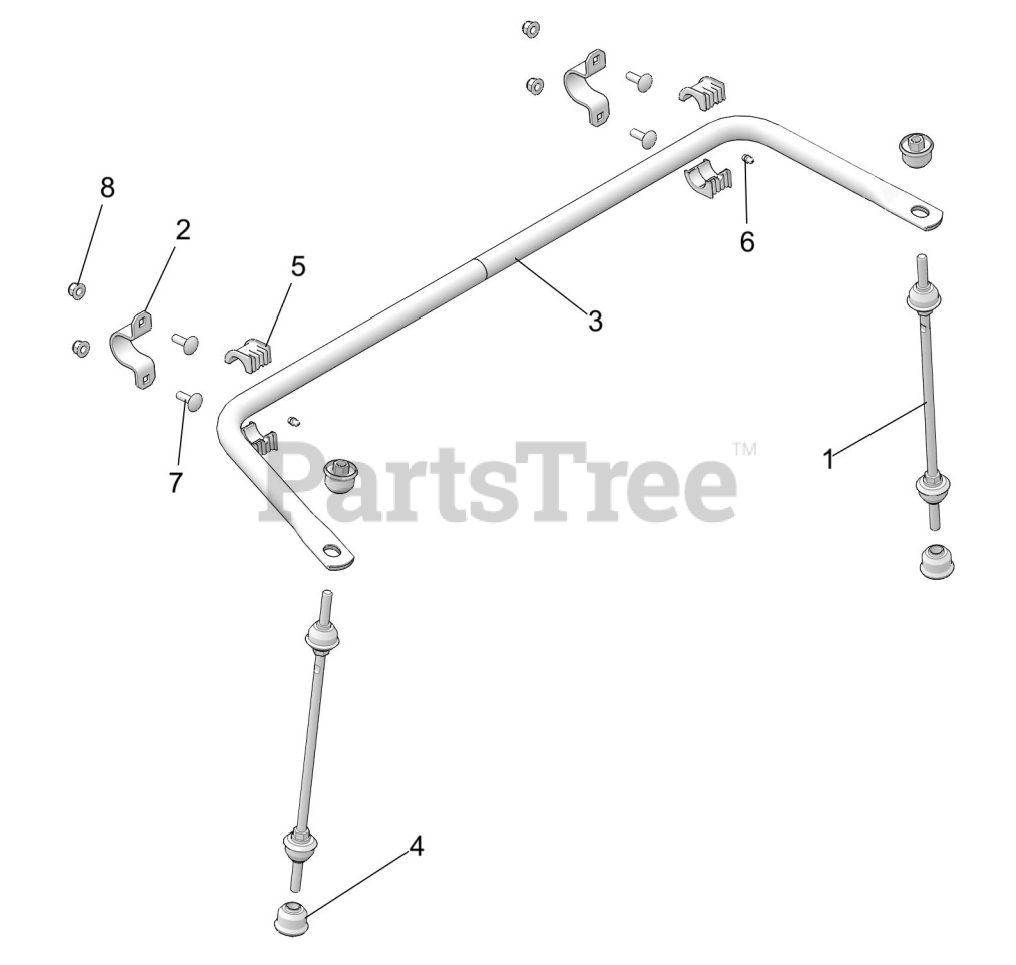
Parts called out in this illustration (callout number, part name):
1	ASM-LINKAGES-STABILIZER BAR
2	BRKT-BUSHING
3	TUBE-STABILIZER,M.BLK
4	BUSHING-LNKG TORBAR-DURO80
5	BUSHING-REAR STABILIZER
6	FITTING-LUB-1/4-28-STR/1792/Y
7	SCR-RHCAR-M8X1.25X25 10.9 ZB3
8	NUT-M8X1.25-FLG-NYLOC-OLIVE D
